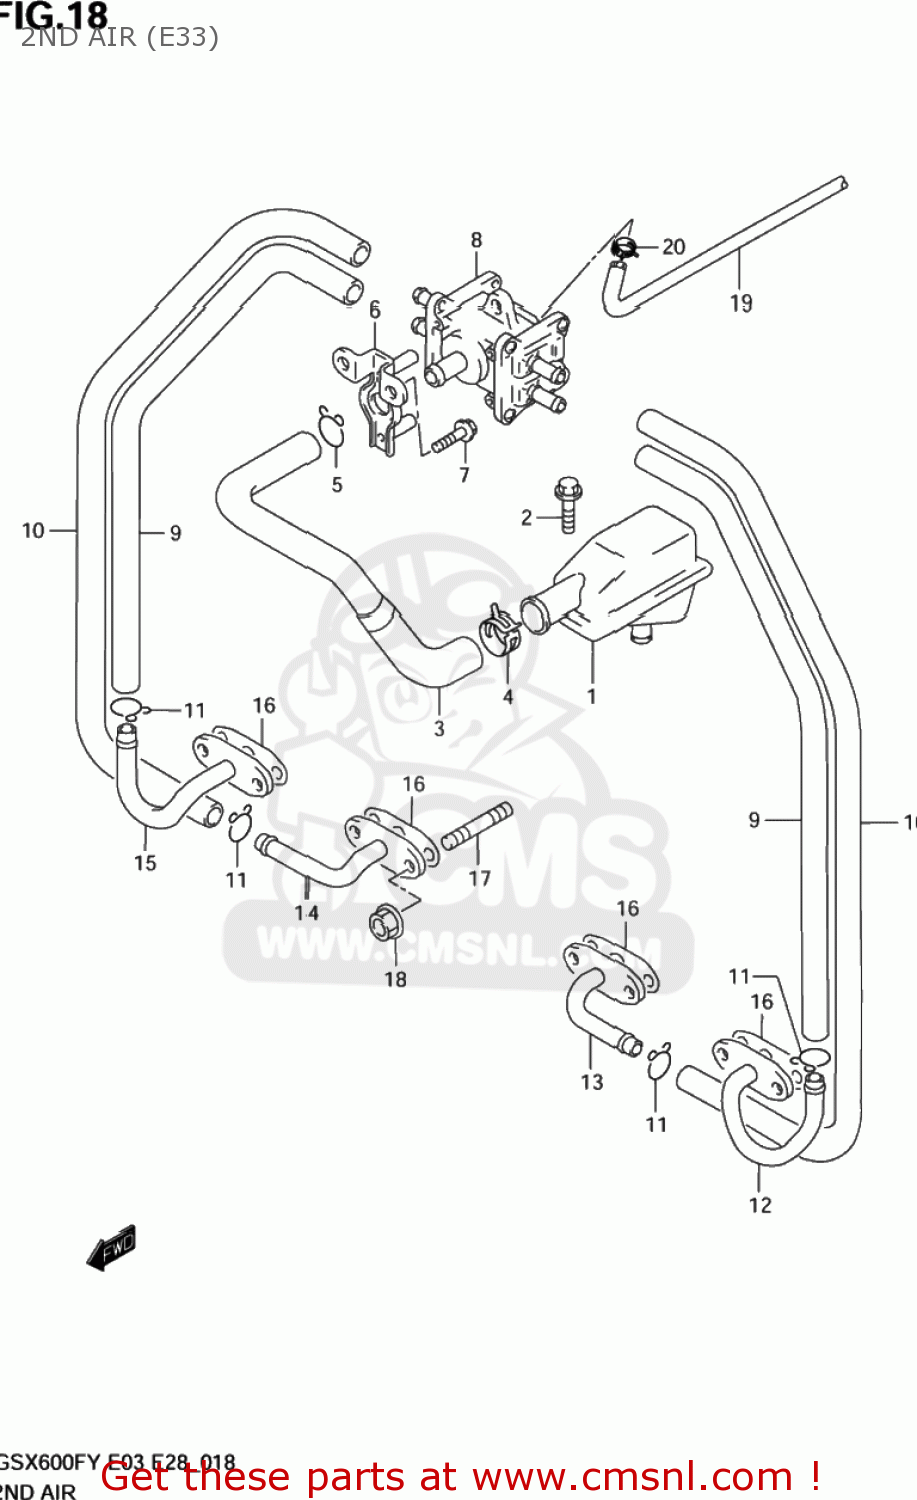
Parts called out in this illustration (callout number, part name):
1	CLEANER ASSY,2ND AIR
2	BOLT
3	HOSE,2ND AIR CLEANER
4	CLIP
5	CLIP
6	BRACKET,2ND AIR VALVE
7	BOLT
8	VALVE ASSY,2ND AIR
9	HOSE,2ND AIR VALVE OUTER
10	HOSE,2ND AIR VALVE INNER
11	CLIP
12	PIPE,2ND AIR NO.1
13	PIPE,2ND AIR NO.2
14	PIPE,2ND AIR NO.3
15	PIPE,2ND AIR NO.4
16	GASKET,2ND AIR PIPE (NAS)
17	STUD BOLT
18	NUT
19	HOSE(4.5X8.5X600)
20	CLIP
